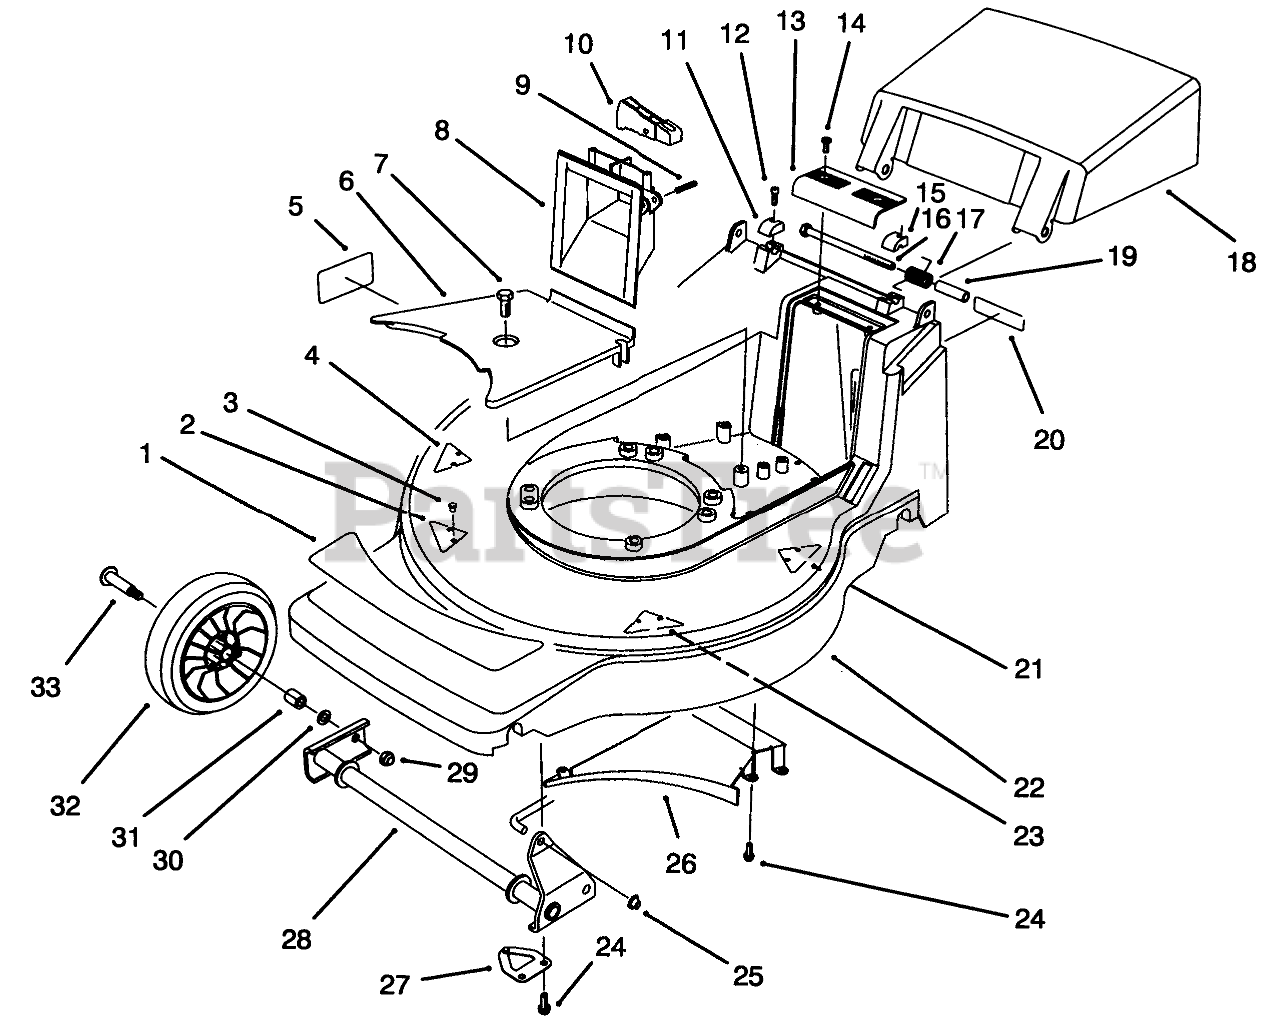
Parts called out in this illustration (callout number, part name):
1	DECAL - DECK
2	KICKER
3	SCREW-PPH
4	KICKER
5	DECAL - DIN/DANGER
6	BELT COVER
7	SCREW-HWHTF
8	GRIP - LOWER
9	PIN-SPIRAL
10	TRIGGER - HOC
11	CAP-HINGE BOLT, RH
12	SCREW-HSH
13	GRIP-UPPER
14	SCREW-PPH, PLASTITE
15	CAP-HINGE BOLT, LH
16	SCREW-HH
17	SPRING-DOOR
18	Door Discharge
19	SPACER-DOOR
20	DECAL FRENCH REGUL.
21	KICKER
22	Housing-Deck (Incl. Ref. #2-5, 20, 21 & 23)
23	KICKER
24	SCREW-HWH
25	NUT-PUSH
26	Ramp-Discharge
27	SHAFT RETAINER ASM
28	FRONT PIVOT WA
29	NUT-HEX
30	WASHER
31	BUSHING
32	7 " WHEEL/TIRE ASM
33	BOLT-WHEEL
